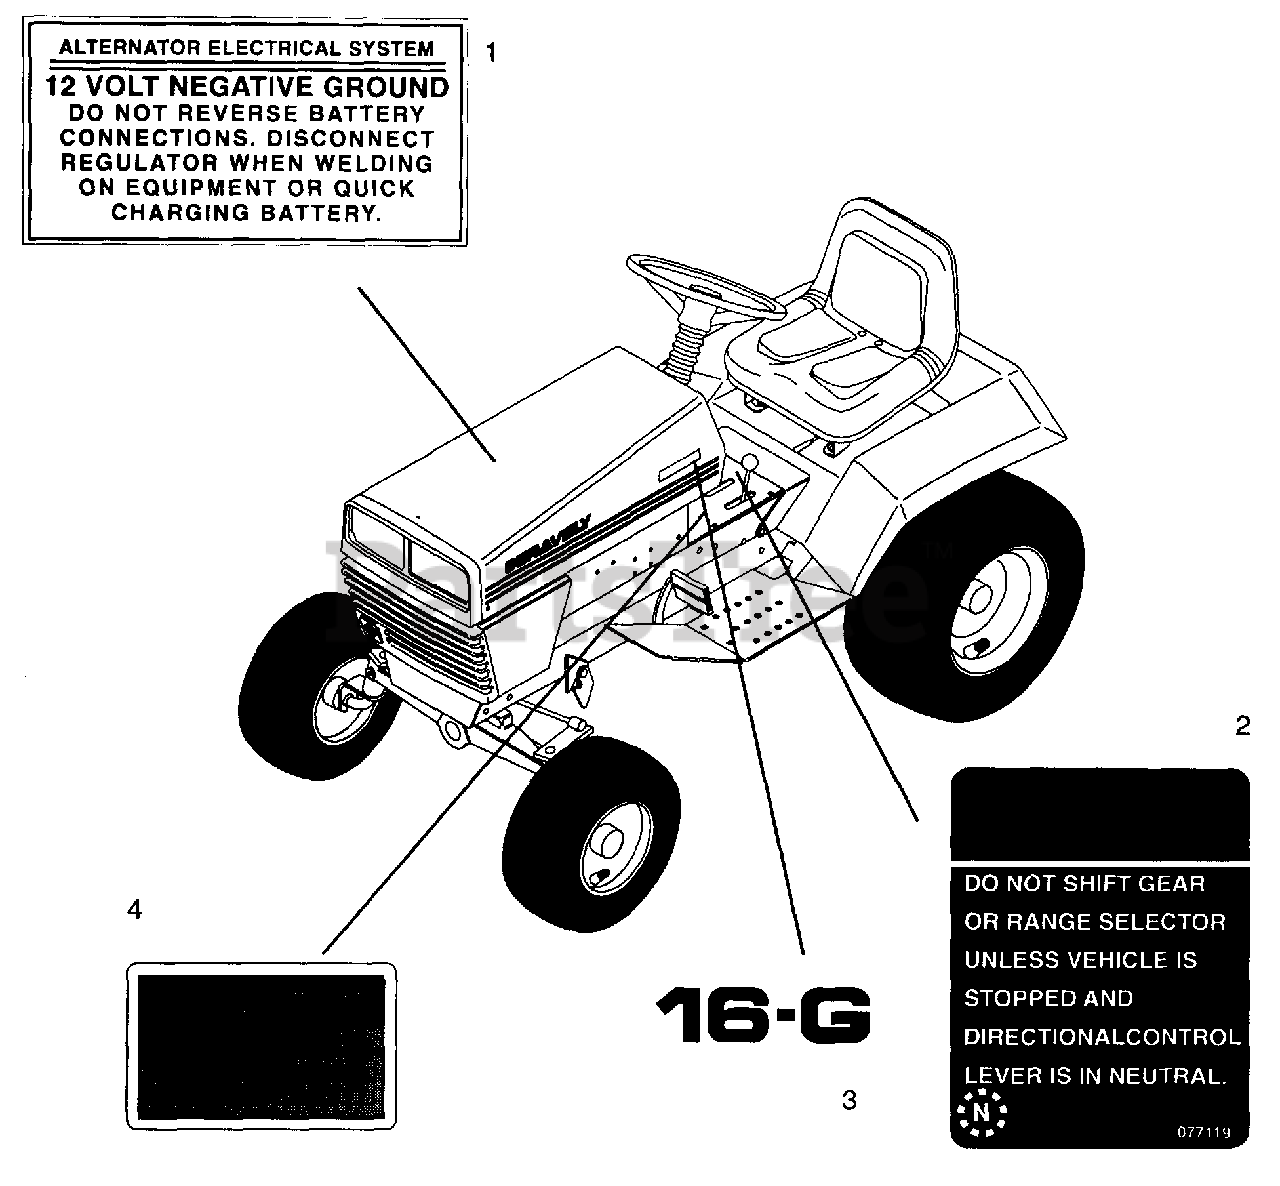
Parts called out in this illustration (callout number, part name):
1	Decal-E-System Warning
2	Decal-Warning
3	Decal-Model 16-G (066,067,070)
3	Decal-Model 18-G (068)
3	Decal-Model 20-G (069)
4	Decal-Caution
